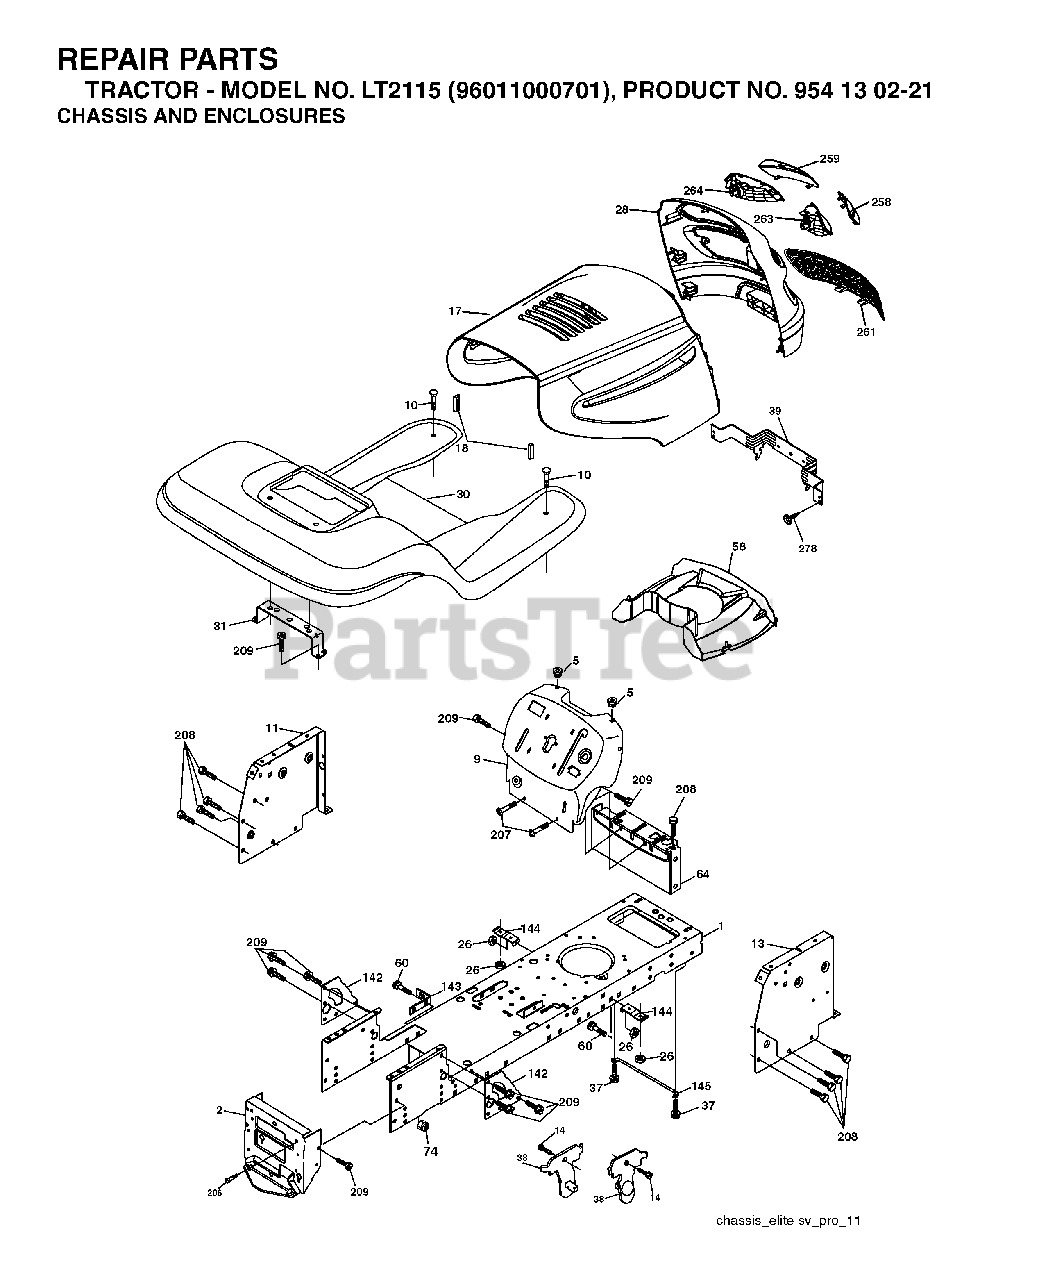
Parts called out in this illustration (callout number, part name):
1	CHASSIS STAMPING
2	DRAWBAR, 12GA
5	BUMPER.RUBBER.HOOD
10	BOLT D
11	PANEL.DASH.LH.LTX
18	BUMPER.HOOD.LARGE.1.75"
26	NUT
38	BRACKET.ASM.PIVOT.MOWER.REAR
39	BRACKET PIVOT LASER
64	DASH LOWER
74	LOCKNUT
142	PLATE REINFORCEMENT
143	BRACKET, SWAYBAR CHASSIS
144	BRKT, FOOT REST
145	ROD PIVOT CHASSIS/HOOD
206	SHOULDER BOLT 5/16-18TT
207	SCREW, 5/16-18 X 1/2
208	SCREW 3/8-16X1/2
209	SCREW, 3/8-16X3/4
212	INSERT.LENS.REFLECTIVE
258	LENS LH
259	LENS LH
260	COVER.LENS.HUSQ.LASER
278	SCREW
